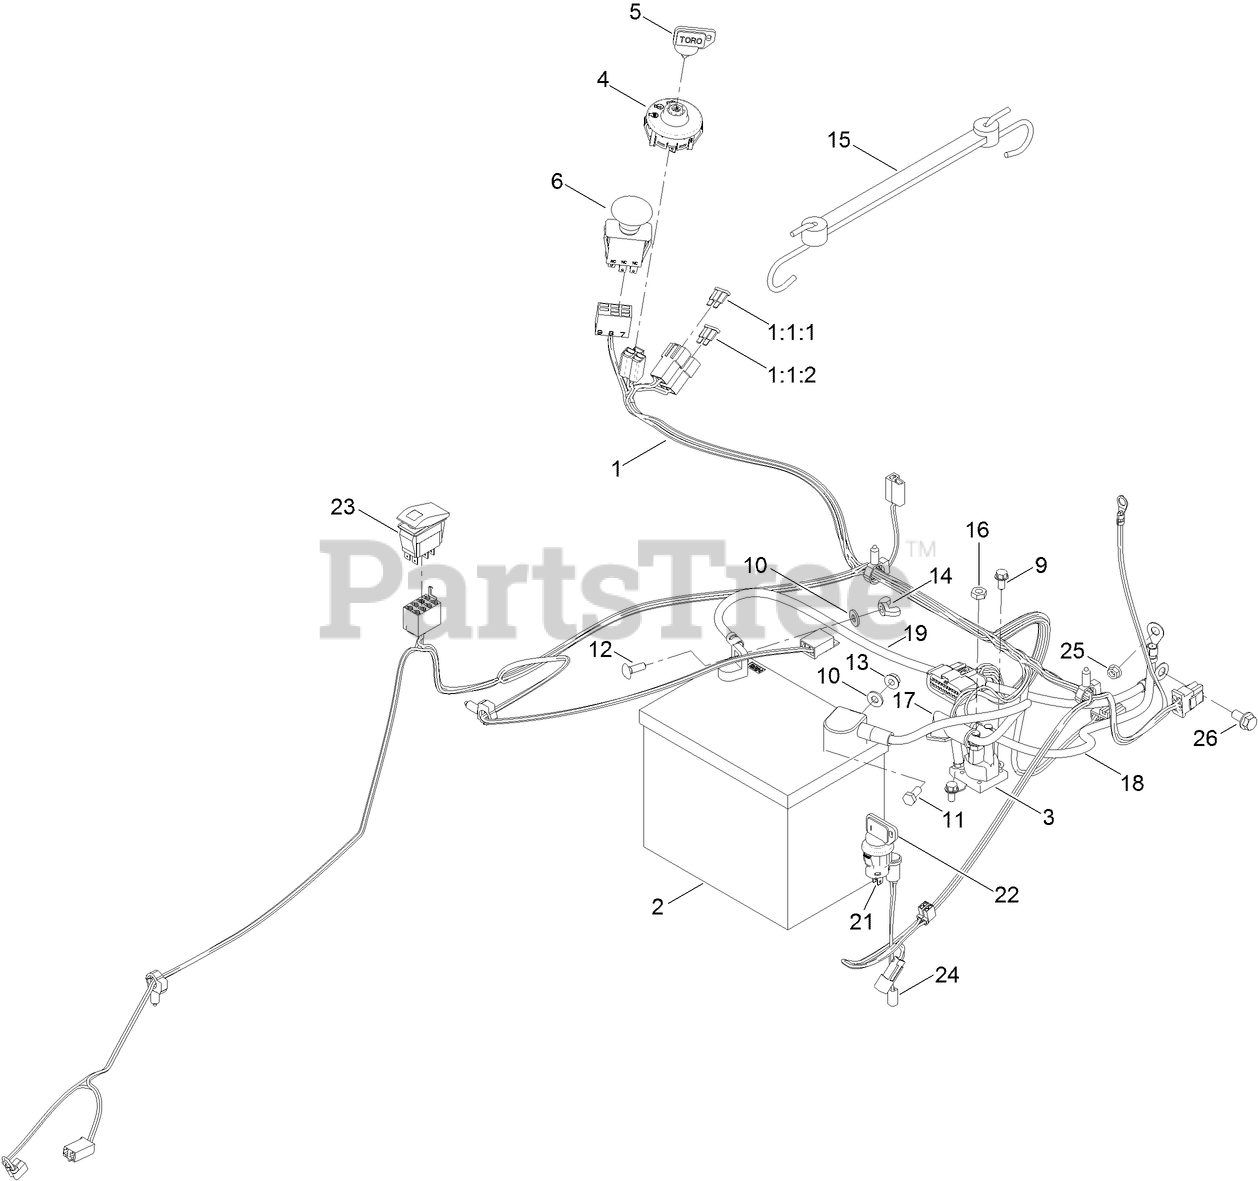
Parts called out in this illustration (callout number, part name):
1	HARNESS-WIRE
1:1	HARNESS-WIRE
1:1:1	FUSE-BLADE, 30 AMP
1:1:2	FUSE-BLADE, 25 AMP
2	BATTERY
3	SOLENOID
4	SWITCH-IGNITION
5	KEY-IGNITION
6	SWITCH-PTO, ON-ON
9	SCREW-HWH
10	WASHER-FLAT
11	SCREW-HH
12	BOLT-CARR
13	NUT-HF
14	NUT-WING
15	HOLDDOWN-BATTERY
16	NUT-JAM
17	CABLE-BATTERY, RED
18	CABLE-BATTERY, POSITIVE
19	CABLE-BATTERY, BLACK
21	SWITCH-MOMENTARY, N.O.
22	KEY-TORO
23	SWITCH-ROCKER, (ON)-OFF-(ON)
24	LIGHT-INDICATOR
25	NUT-HF
26	SCREW-HHF
